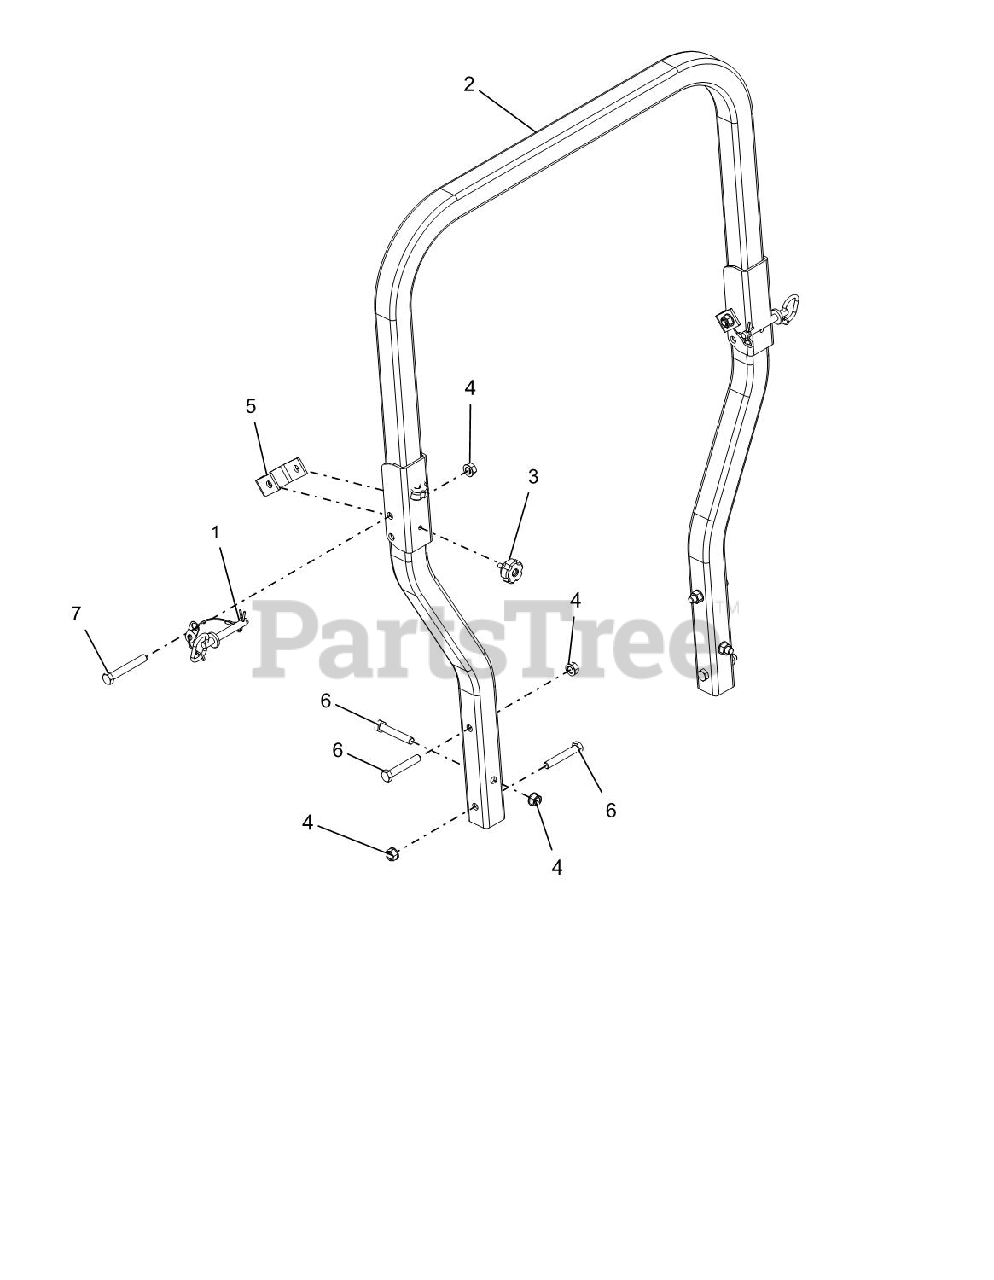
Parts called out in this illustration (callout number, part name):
1	ASSY, ROPS PIN/LANYARD
2	ROPS, PRO-TURN 400 REPLACEMENT
3	KNOB, ROUND 5/16-18 X .750
4	NUT-LK-TOP-FLG .50-13 YWZC
5	BRKT, ROPS STOP
6	BLT-HEX .50-13X3.00 GR5 YWZC
7	BLT-HEX .50-13X3.50 GR5 YWZC
